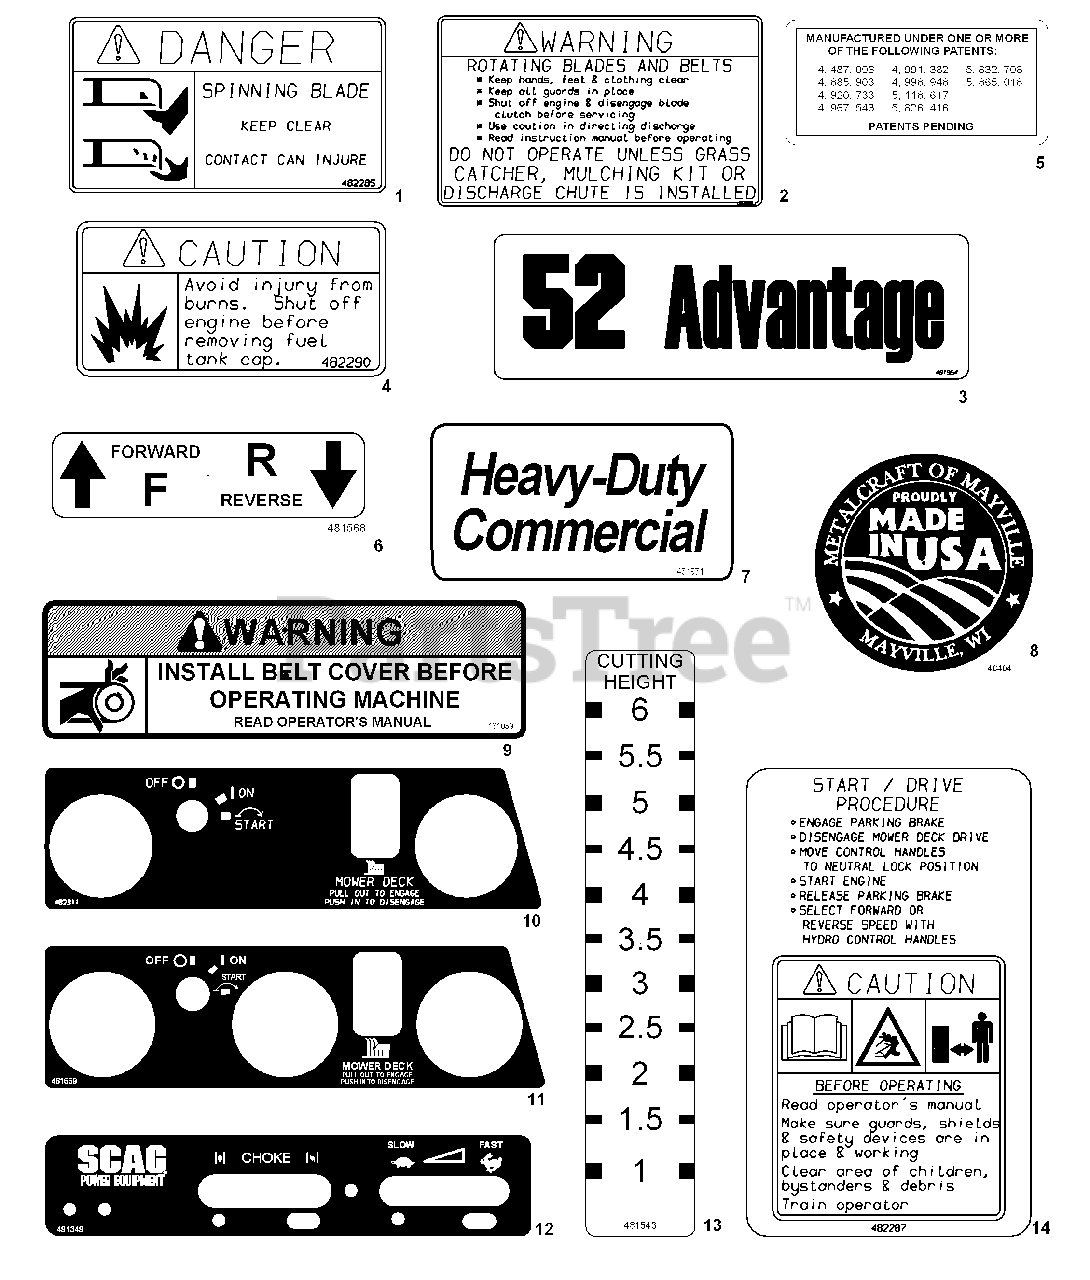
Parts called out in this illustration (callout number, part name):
1	Decal, Danger-Spinning Blades
2	Decal, Warning-Rotating Blades
3	Decal, 52 Advantage
4	Decal, Fuel Tank
5	Decal, Patents
6	Decal, Traction Control
7	Decal, Heavy Duty Commercial
8	Decal, MetalCraft-Made In USA
9	Decal, Belt Cover
10	Decal, Instrument Panel-Upper
11	Decal, Instrument Panel-Upper
12	Decal, Instrument Panel-Lower
13	Decal, Cutting Height
14	Decal, Start/Drive Procedure
